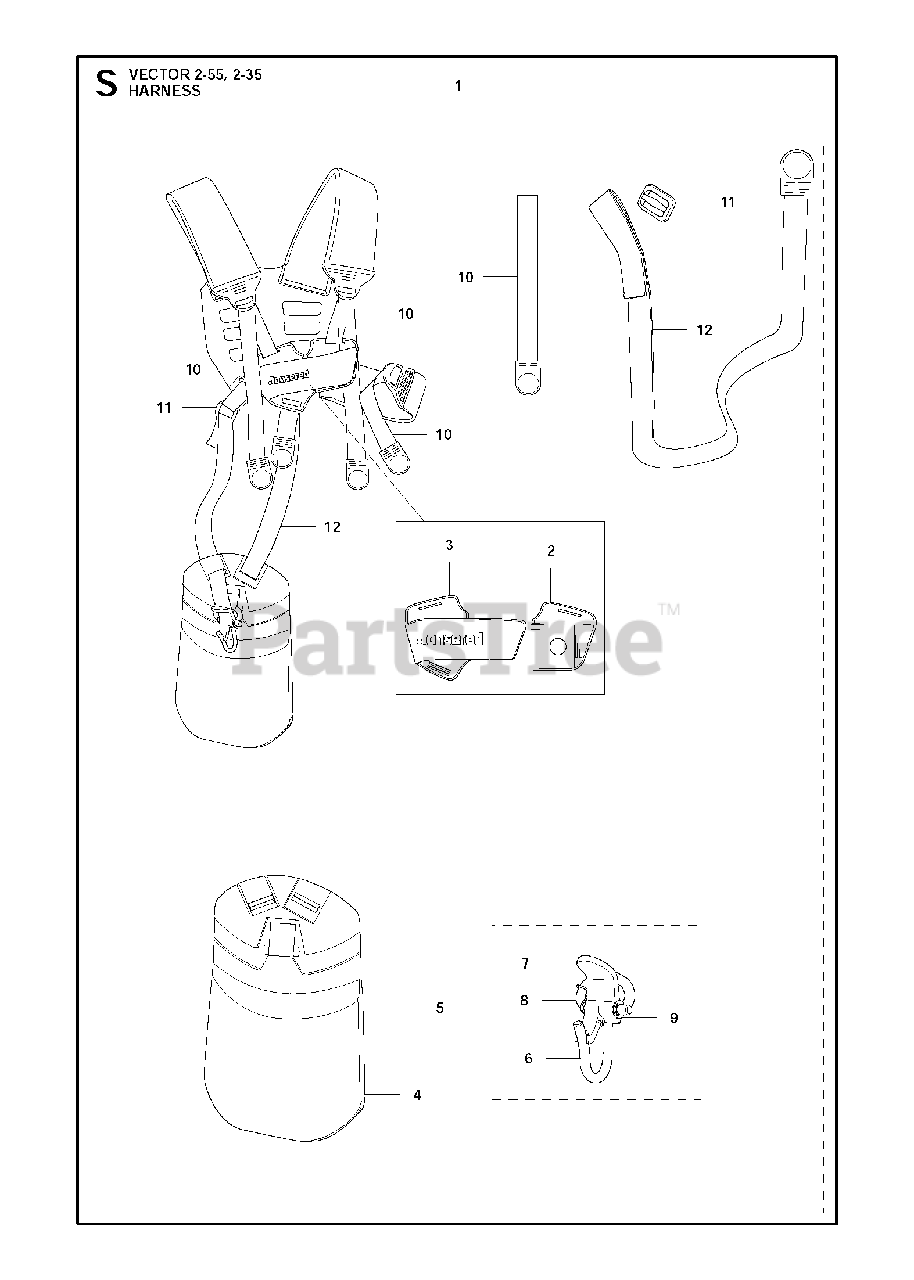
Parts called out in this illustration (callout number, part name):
1	HARNESS "VECTOR" 2-55
1	HARNESS COMPLETE
2	FRONT PIECE
3	FRONT PIECE
4	PROTECTOR
5	HARNESS HOOK, COMPLETE
6	HOOK
7	CATCH *
8	SPRING
9	E-RING 5
10	BAND
11	CLIP
12	BAND
